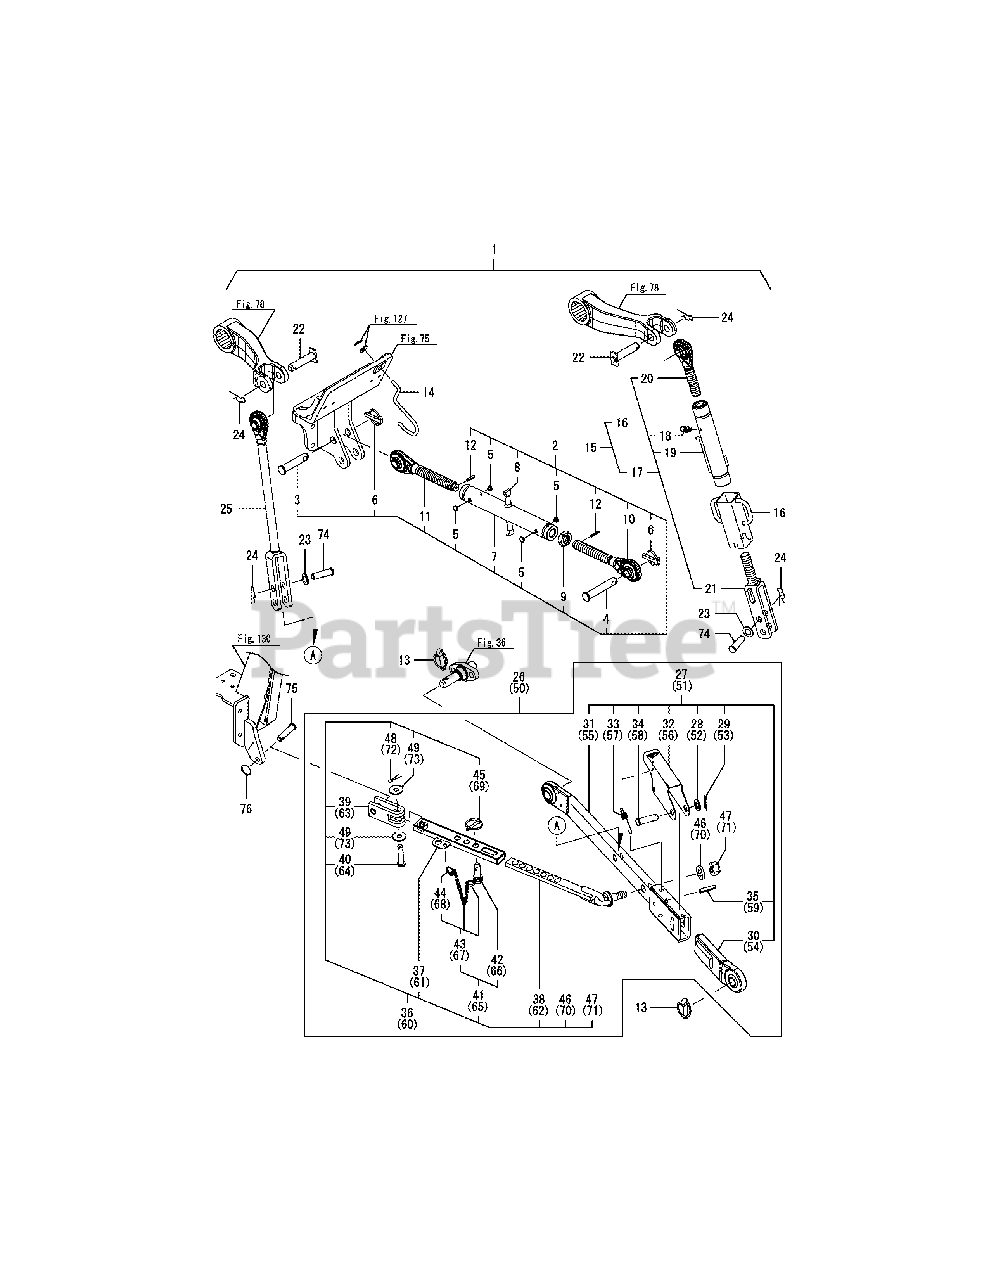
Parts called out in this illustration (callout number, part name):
2	LINK ASSY, TOP
6	LYNCH PIN ASSLY
7	TURNBACKLE ASSY
10	EYEBOLT ASSY, RH
11	EYEBOLT ASSY, LH
13	LYNCH PIN ASSLY
15	LINK ASSY, LIFT R.H.
17	LINK ASY, LIFT R
19	TURN BUCKLE CMP
20	BOLT ASSY, EYE
21	YOKE ASSY, LIFT R.H.
24	SNAP PIN 13-19
25	LIFT LINK L CMP
26	LINK & CHAIN L ASY
27	LINK ASSY, LOWER LH
29	COTTER,PIN, 4.0X32
30	LOWER MEMBER RL CMP
31	LOWER MEMBER F ASSY
36	STABILIZER ASSY
37	TUBE CMP, OUTER
38	PLATE CMP, INNER
45	LYNCH PIN ASSY
47	NUT 18, NYLON LOCK
50	LINK & CHAIN R ASSY
51	LINK ASSY, LOWER RH
53	COTTER,PIN, 4.0X32
54	LOWER MEMBER RR CMP
55	LOWER MEMBER F ASSY
60	STABILIZER ASSY
61	TUBE CMP, OUTER
62	PLATE CMP, INNER
69	LYNCH PIN ASSY
71	NUT 18, NYLON LOCK
